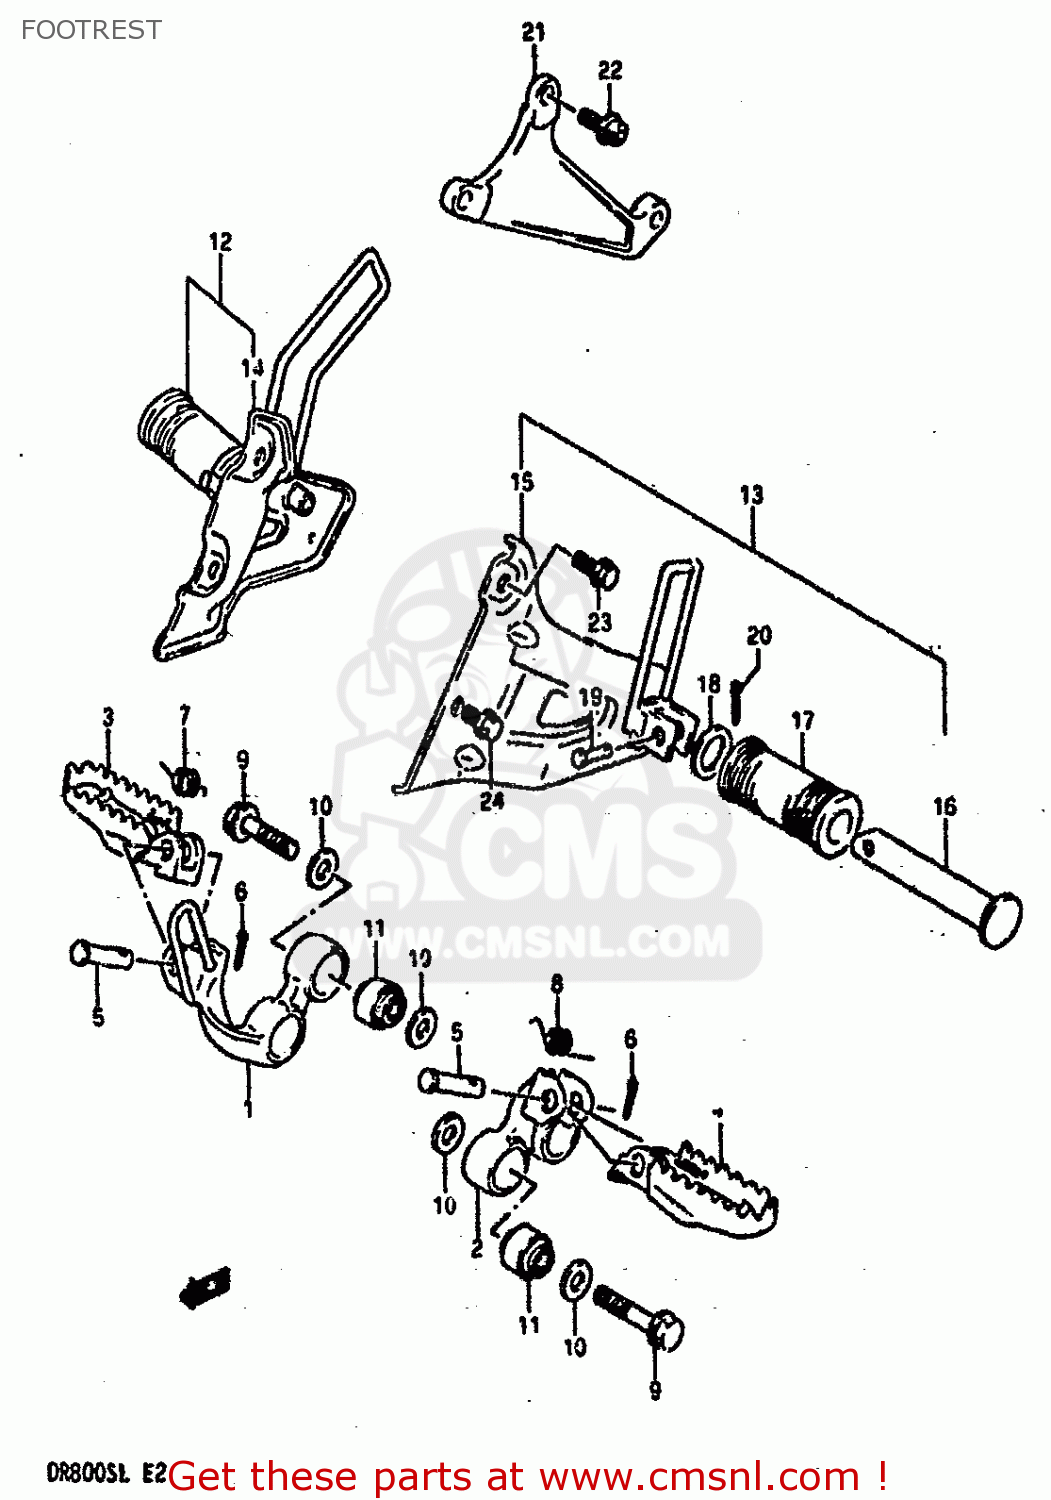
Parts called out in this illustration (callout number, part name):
1	BAR,FOOTREST RH (BLACK)
2	BAR,FOOTREST LH (BLACK)
3	FOOTREST,FR,R
4	FOOTREST,FR,L
5	PIN
6	PIN 20X20
7	SPRING
8	SPRING
9	BOLT
10	WASHER(10.1X23X2.3)
11	BUSHING 10X28.1X19
12	FOOTREST,PILLION RH (WHITE)
13	FOOTREST,PILLION LH (WHITE)
14	HOLDER,RH (WHITE)
15	HOLDER,LH (WHITE)
16	BAR,FOOTREST RUBBER
17	RUBBER,PILLION FOOTREST
18	WASHER (19.5X32X2)
19	PIN
20	PIN
21	BRACKET,MUFFLER (SILVER)
22	BOLT
23	BOLT
24	BOLT,LOWER LH
